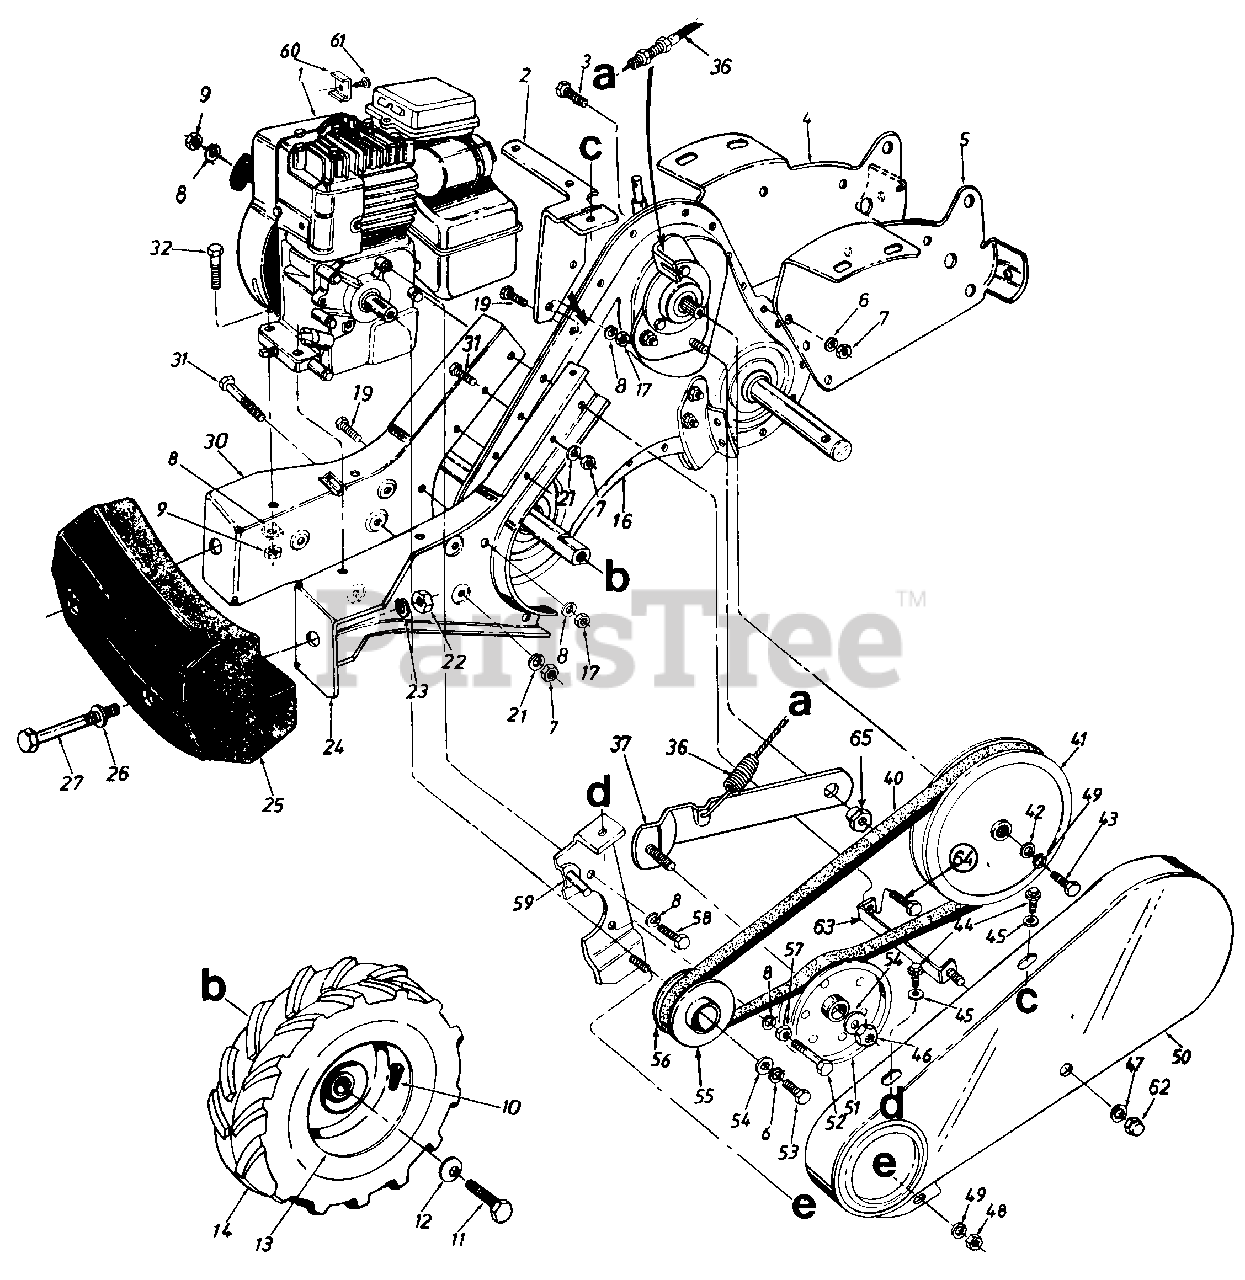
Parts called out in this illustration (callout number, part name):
1	Engine
7	Hex Nut 3/8-16 Thd.
8	L-Wash. 5/16" I.D.
9	Hex Nut 5/16-18" Thd.
10	Air Valve
11	Hex Bolt 5/16-24 x .62" Lg.
12	Bell-Wash. .345" I.D. x .88"
13	Wheel Rim Ass'y. Only
14	L.H. Wheel Ass'y. Comp.
17	Hex Nut 5/16-18 Thd.
19	Hex Bolt 5/16-18 x .75" Lg.
21	L-Wash. 3/8" I.D.-H.D.
22	Hex Nut 1/2-13 Thd.
23	L-Wash. 1/2" I.D.
26	Fl-Wash. .510" I.D. x 1.0"
27	Hex Bolt 1/2-13 x 5.00" Lg.
32	Hex Bolt 5/16-18 x 1.50"
36	Clutch Control Cable 46" Lg.
37	Idler Bracket Ass'y.
40	"V"-Belt
41	Fl-Pulley 8" O.D.
42	Fl-Wash. 1/4" I.D. x .93" O.D.
43	Hex Bolt 1/4-28 x .75" Lg.
44	Hex Wash. Hd. S-Tap Scr. 1/4-20 x .50" Lg.
45	Fl-Wash. .281" I.D. x .625"
46	Hex Cent. L-Nut 3/8-24 Thd.
47	Fl-Wash. .266" I.D. x .625" O.D.
48	Hex Nut 1/4-20 Thd.
49	L-Wash. 1/4" I.D.
51	Fl-Idler w/Flanges 3.75" O.D.
52	Hex Bolt 5/16-24 x 1.75"
53	Hex Bolt 3/8-24 x 1.00" Lg.
54	Fl-Wash. 3/8" I.D. x 1.00"
55	Outer Engine Pulley Half
56	Inner Engine Pulley Half
57	Hex Nut 5/16-24 Thd.
58	Hex Bolt 5/16-24 x .62" Lg.
61	Hex Sems Scr. #10-32 x .62"
62	Hex Cap Nut 1/4-28 Thd.
63	Belt Cover Brkt. Ass'y.
64	Hex Bolt 5/16-18 x 1" Lg. (Gr. 5)
65	Shld. Nut
